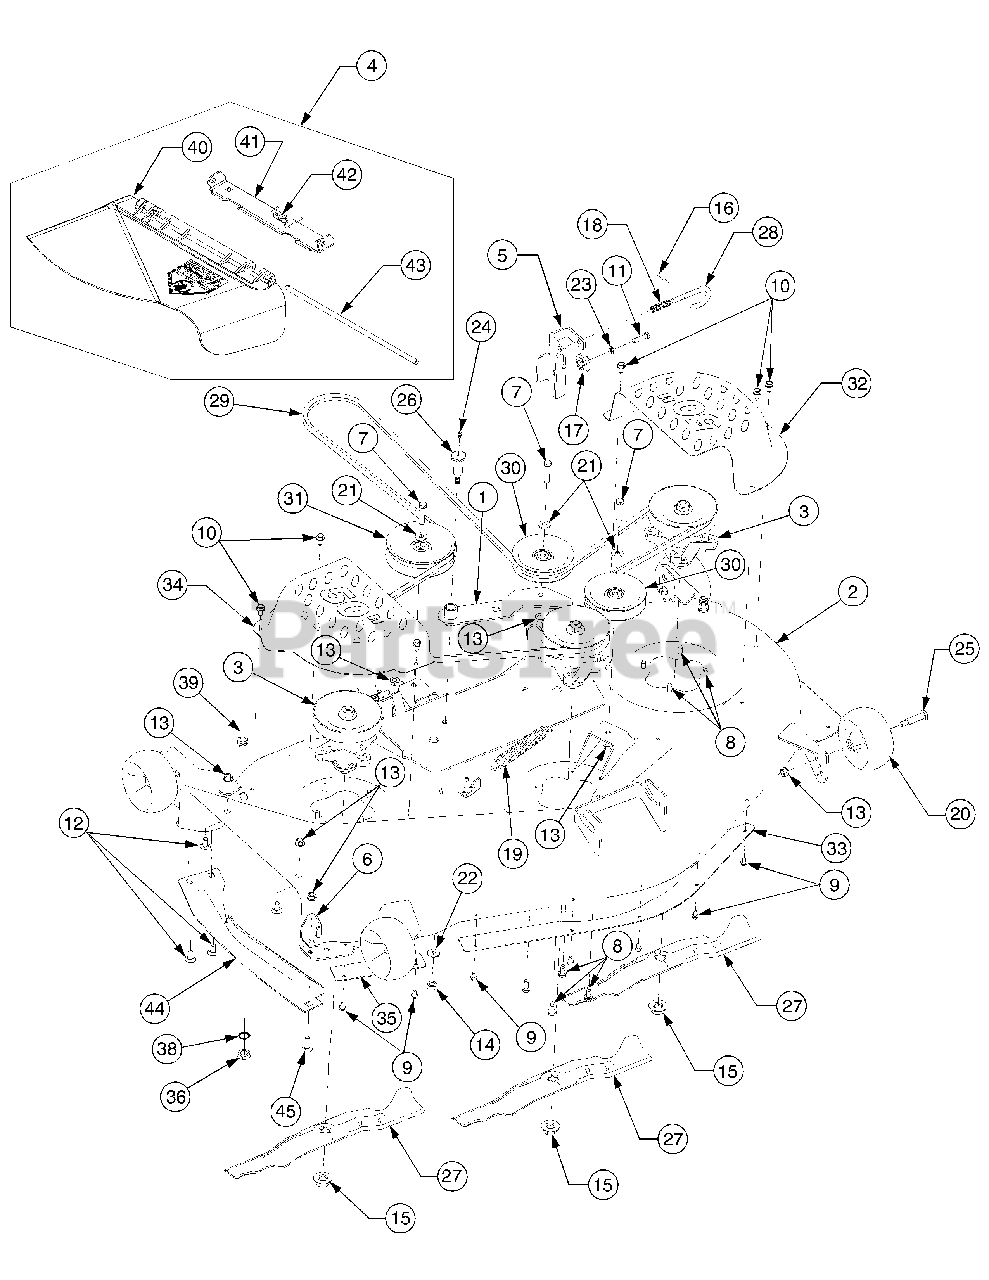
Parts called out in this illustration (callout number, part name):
3	Spindle Assembly
4	Chute Assembly, Discharge
7	Screw, Hex Cap, 3/8-16 x 1.75 GR5
8	Screw, Hex Wash. Hd. Tapp 5/16-18 x .75
9	Screw, Hex Wash. Hd. Tapp 1/4-20 x .5
10	Screw, Hex Wash. Hd. Tapp 5/16-12 x .75
11	Screw, Hex Cap, 5/16-18 x 1.25 GR5
12	Screw, Carriage, 3/8-16 x .75
13	Nut, Hex Flange Lock, 3/8-16 GRF
14	Nut, Hex, 7/16-14
15	Nut, Hex Flange, 5/8-18
16	Pin, Cotter, 1/8 x 1.25
17	Gear, Deck Adjustment
18	Spring, Compression
19	Spring, Extension, .94 Dia. x 6.74
20	Wheel, Deck Ball, 5.0
21	Washer, Flat, .38 x .93 x .110 HT
22	Washer, Bell, .45 x 1.0 x .062
23	Washer, Lock, 5/16
24	Fitting, Lube, 3/16 Drive
25	Screw, Shoulder, .498 x 1.53:3/8-16
26	Screw, Shoulder, .68 x 1.59
27	Blade, 2 in 1, 17.9 Lg
28	Rod, Deck Hanger
29	Belt V, Type A Sec x 134
30	Pulley, Idler, 4.06 Dia
31	Pulley, Idler,
36	Nut, Hex, M16-1.5
38	Washer, Lock
39	Plug, Screw, M16 x 1.5
40	Chute, Deflector
41	Bracket, Chute Mounting
42	Spring, Torsion
45	Screw, Carriage, 3/8-16 x 1.0
777D08313	Graphic, 50 inch cut, White
